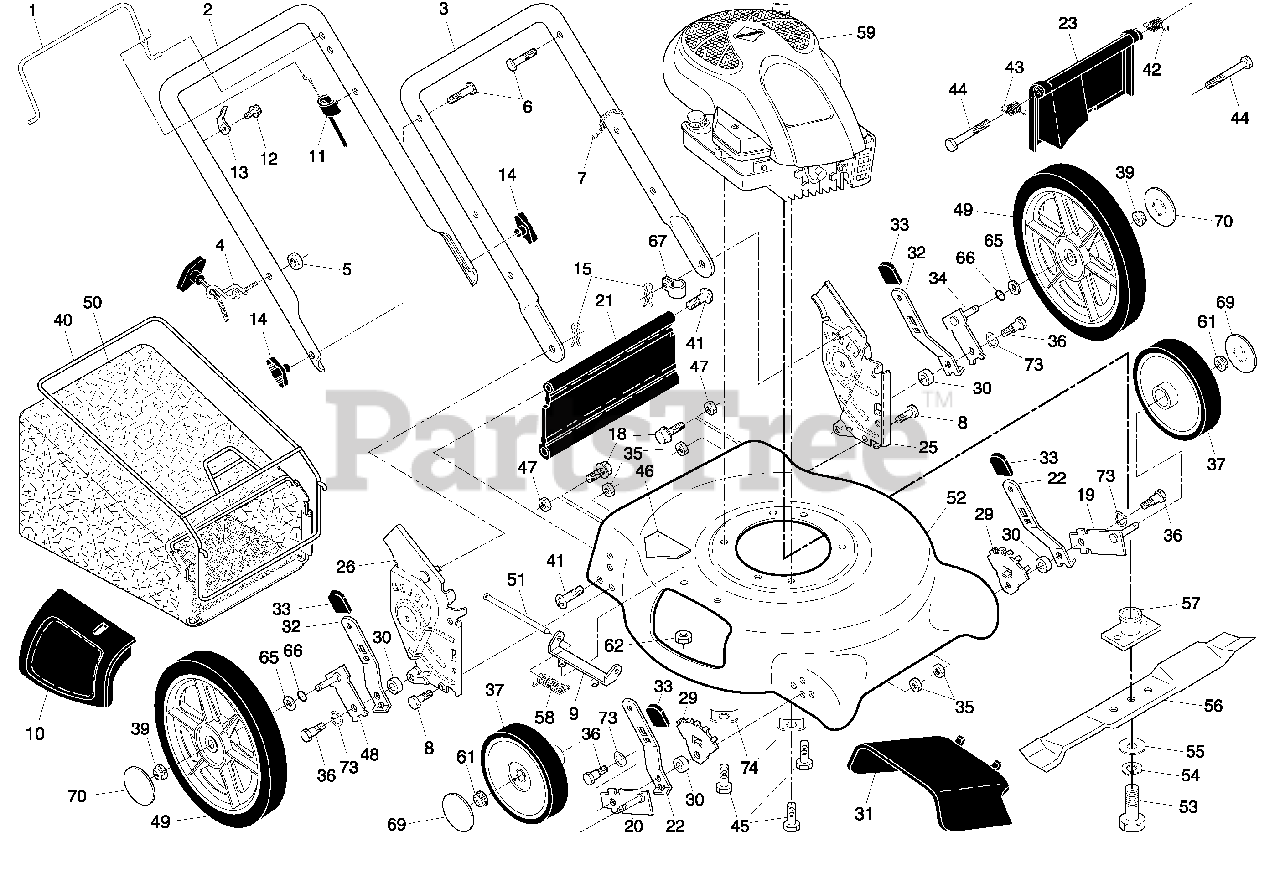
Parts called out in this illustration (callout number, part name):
1	Control Bar
2	Upper Handle
3	Lower Handle
4	Rope Guide
5	Locknut, Hex 1/4-20
6	Handle Bolt
7	Wire Tie
8	Hex Bolt 5/16-18 x 3/4
9	Mounting Bracket, Mulcher Door
10	Mulcher Door
11	Engine Zone Control Cable
12	Hex Washer Head Screw #10-24 x 1/2
13	Up-Stop Bracket
14	Handle Knob
15	Hairpin Cotter
18	Screw
19	Axle Arm Assembly, Front, LH
20	Axle Arm Assembly, Front, RH
21	Rear Skirt
22	Selector Spring, Front
23	Rear Door Assembly
24	Locknut, Hex 5/16-18
25	Handle Bracket, LH
26	Handle Bracket, RH
29	Wheel Adjusting Bracket
30	Spacer
31	Deflector, Discharge
32	Selector Spring, Rear
33	Selector Knob
34	Axle Arm Assembly, Rear, LH
35	Locknut, Hex 5/16-18
36	Shoulder Bolt 5/16-18
37	Wheel & Tire Assembly, Front, 8"
38	Shoulder Bolt
39	Flanged Locknut
40	Frame, Grassbag
41	Hinge Screw
42	Spring, Rear Door, LH
43	Spring, Rear Door, RH
44	Bolt, Rear Door
45	Screw, Hex Head Thread Rolling Screw 3/8-16 x 1
46	Danger Decal
47	Nut, Hex
48	Axle Arm Assembly, Rear, RH
49	Wheel & Tire Assembly, Rear, 12"
51	Rod, Hinge
52	Kit, Lawn Mower Housing
53	Hex Head Screw, Grade 8, 3/8-24 x 1-3/8
54	Helical Lockwasher
55	Hardened Washer
56	21" Blade
57	Blade Adapter
58	Spring, Hinge Rod
61	Flanged Locknut
62	Nut, Hex
65	Washer, Flat 3/8
66	O-Ring
67	Clip, Cable
69	Hubcap, Front Wheel
70	Hubcap, Rear Wheel
73	Washer, Curved, Cylindrical
74	Washer, Special, Engine
74	Operator's Manual, English
74	Operator's Manual, French
74	Repair Parts Manual
